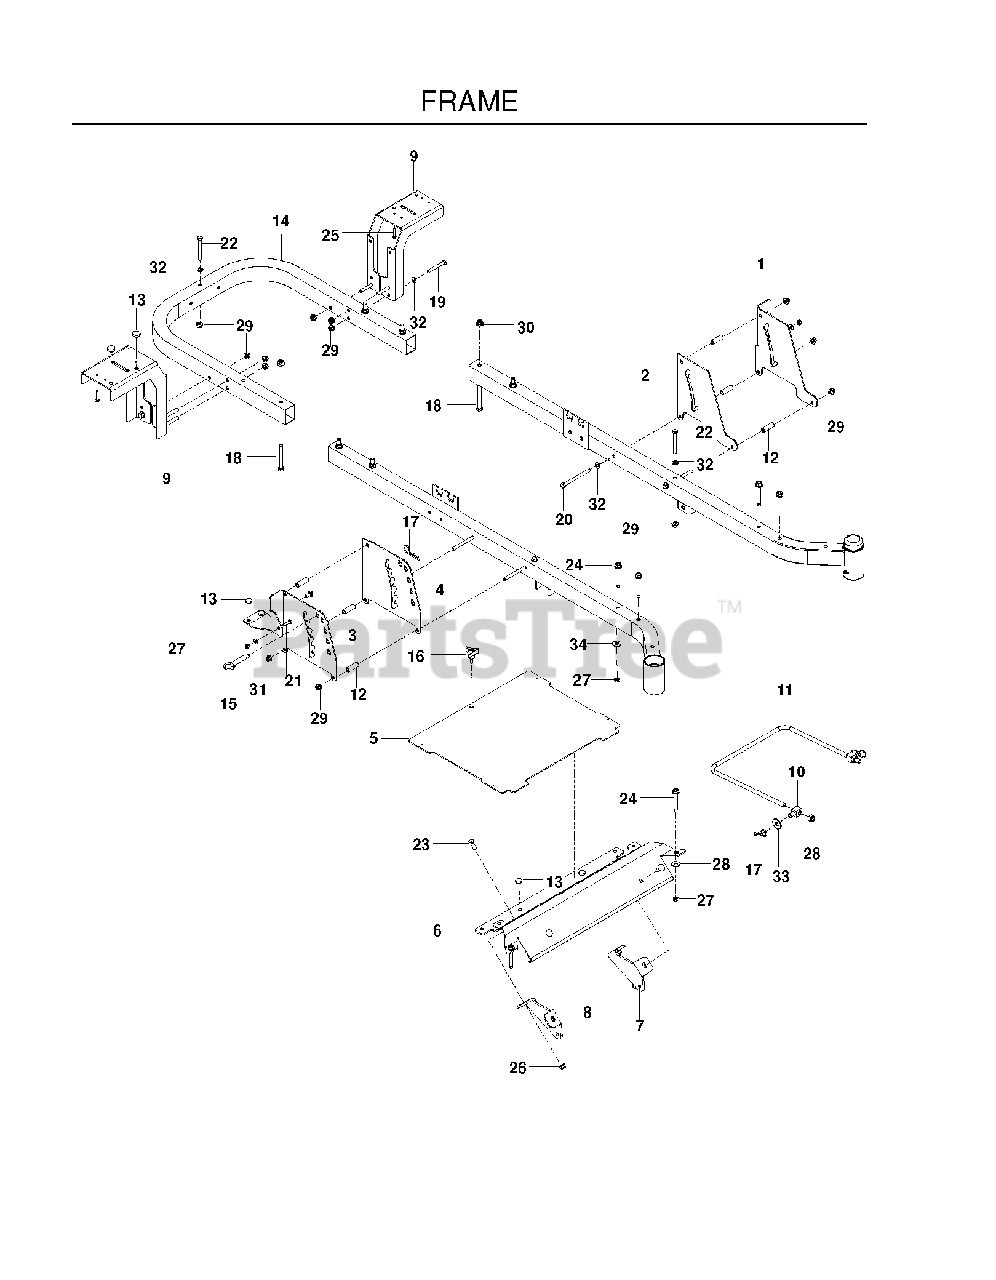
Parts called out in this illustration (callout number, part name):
1	PLATE, OUTER BRAKE, BLACK
2	PLATE, BRAKE LATCH, BLACK
3	PLATE, DECK HEIGHT, BLK EZ
4	PLATE, DECK HEIGHT, BLACK
5	PLATE, FOOT, YLW
6	FOOT, REST, MED YLW
7	MOUNT, STRUT, RT, BLK
8	MOUNT, STRUT, LT, BLK
9	SUPPORT, FENDER, BLACK
11	LINK, FRONT SUSP.
12	SPACER, .334 ID X .5 OD X 1.5
13	GROMMET, BUMPER
14	FRAME TUBE, REAR, YLW
15	HITCH PIN
16	KNOB W/STUD
17	HAIRPIN #4
18	HCS 3/8C X 3
19	CAPSCREW
20	HCS 5/16C X 4
21	HCS 1/4C X 1
22	HCS 5/16C X 2-3/4
23	RHSNB 3/8C X 1
24	ENGINE BOLT, SPECIAL
25	SCR #10-12X1-1/2HEX WASH HD ZD
26	NUT 1/4-20 NYLOC
27	NUT HEX 3/8-16 NYLON, THIN
28	7/16-14 HEX NUT W/NYL RING ZD
29	5/16-18 NYLOC FLANGE NUT
30	NUT 3/8-16 HEX FLG NYLOC ZD
31	WASHER 1/4 SAE
32	FLAT WASHER 5/16 SAE
33	WASH USS FLAT 1/2
34	WASHER 3/8 FLAT
